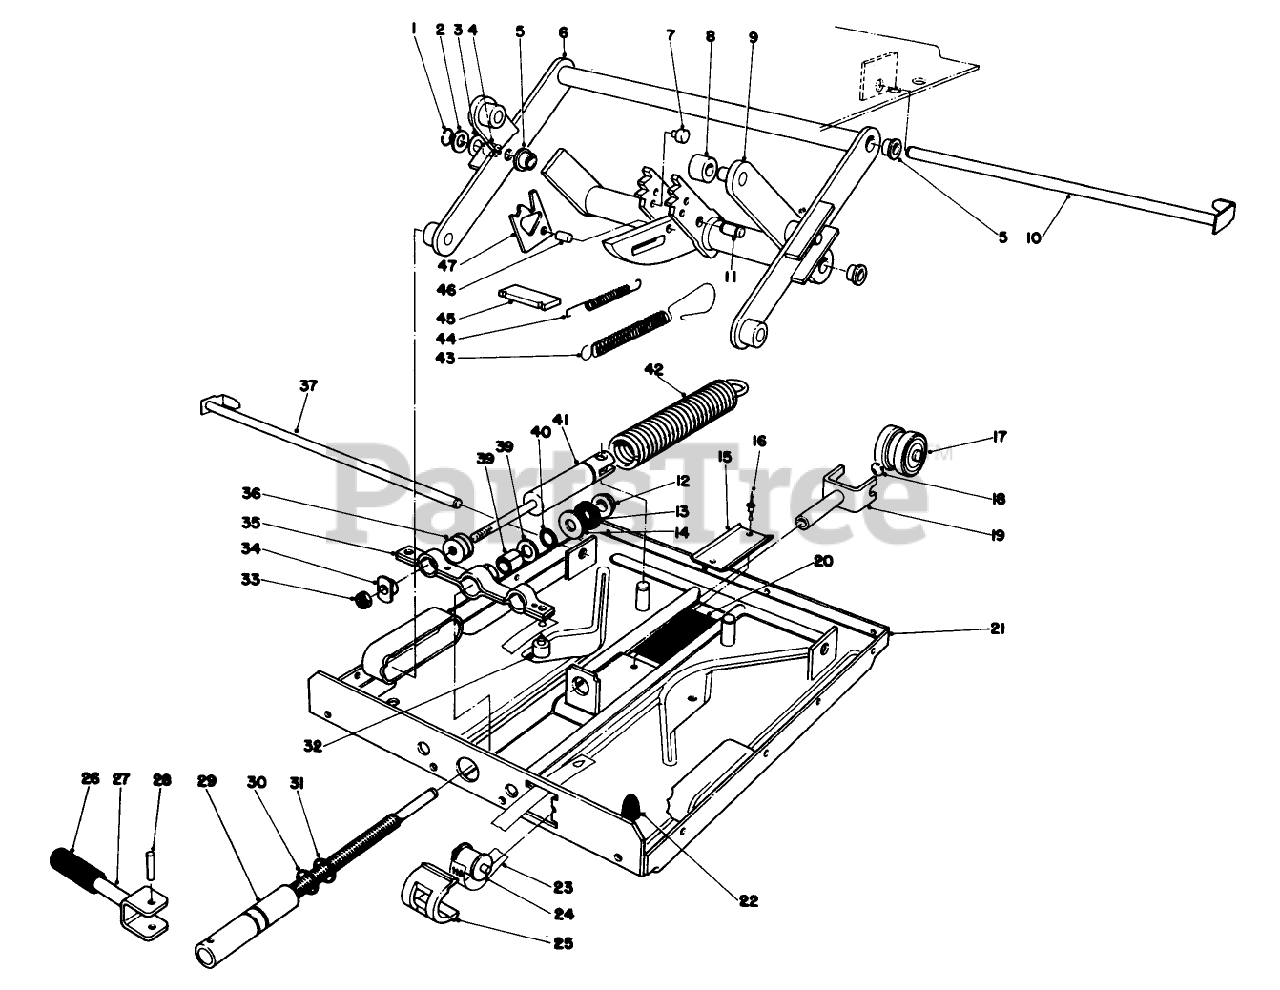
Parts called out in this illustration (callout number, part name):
1	Washer
2	Washer
3	Washer
4	WAVE WASHER
5	FRONT WEIGHT B
6	SPRING-BRAKE
8	LOCKNUT-CONDUIT
9	ASSY-QUADRANT
11	SPRING-EXTENSION
12	Sleeve
13	Idler Arm
14	Washer 8 MM
15	U-Track
16	Plate 4X10MM
17	Trible-Bearing
18	Washer
20	Rubber Plate
21	Lower Suspension Plate-Complete (Incl. Ref. #15-16 & 20)
22	Bumper
23	PLATE-HOODSTAND REAR
24	Roller
25	Guide Sleeve
26	Handle
27	Toggle
28	Grooved Pin 5X28MM
30	Rubber Ring 14MM Black
31	Rubber Ring 14MM Red
33	ASSY-DIFFERENTIAL
34	BUSHING PTO PIVOT
35	Spring Bracket
36	DECAL HOOD RH
37	SPACER-BUSHING
38	Sleeve 14x1x19MM
39	Washer
40	Thrust Needle Bearing
41	Brake Pad
42	Coil Spring
43	Coil Spring
44	Coil Spring
45	WASHER
47	Footrest RH
